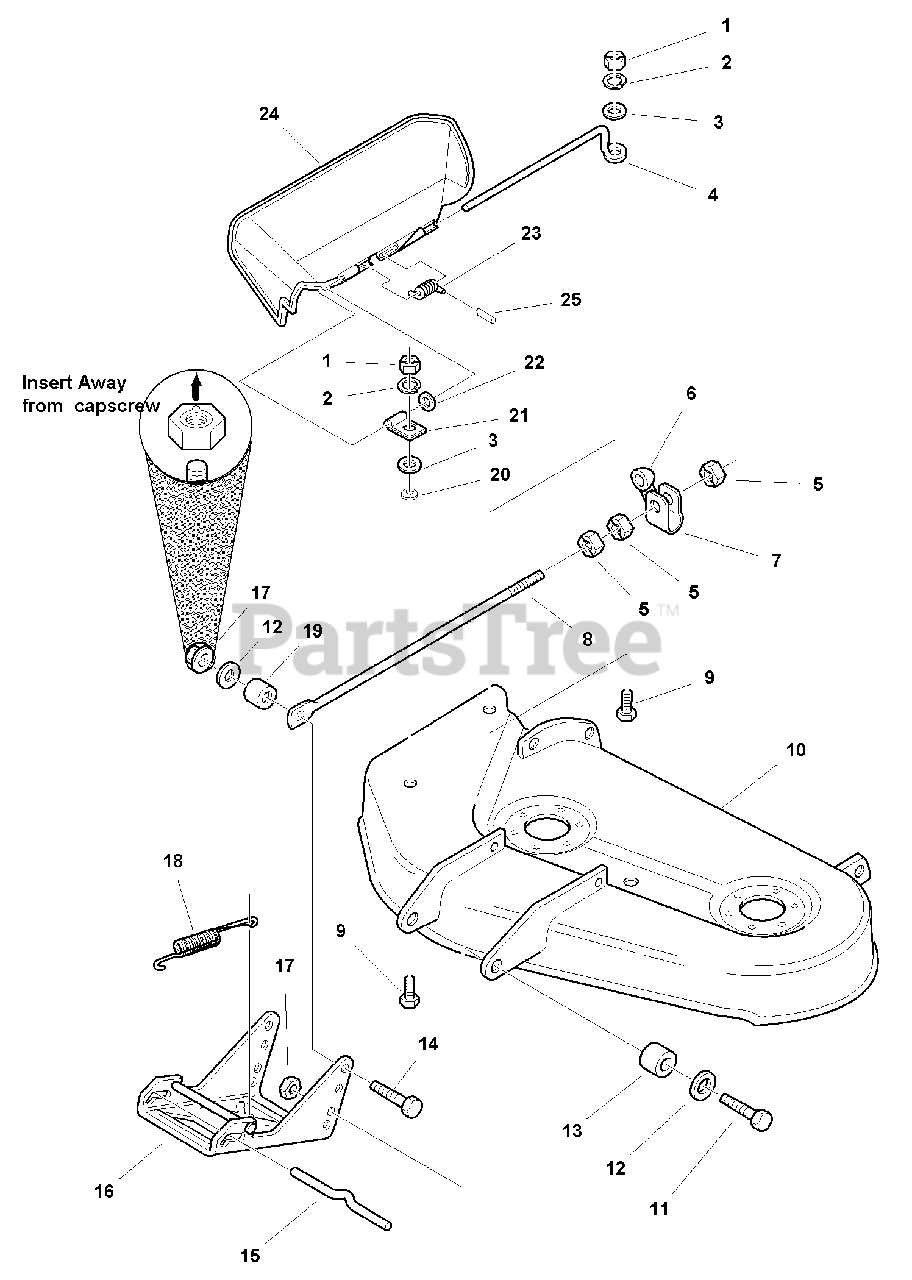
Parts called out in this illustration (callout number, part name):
1	NUT, Hex, 1/4-20
3	WASHER, Flat, 17/64 x 27/32 x 1/8
4	ROD, Deflector, Front
5	JAMNUT, Hex, 1/2-13
6	SPACER
8	ROD, Adustment
9	CARRIAGE BOLT, 1/4-20 X 7/8
10	HOUSING ASSEMBLY, 34" (Orange)
10	HOUSING ASSEMBLY, 34" (Black)
11	CAPSCREW, Hex Head, 3/8-16 x 1-3/8
12	WASHER, Flat, 3/8
14	CAPSCREW, Hex Head, 3/8-16 x 1
15	ROD, Latch, Hitch
16	HITCH ASSEMBLY
17	NUT, Hex Lock, Alm Insert, 3/8-16
20	PUSHNUT
24	DEFLECTOR, Plastic
25	CAP, Spring End
